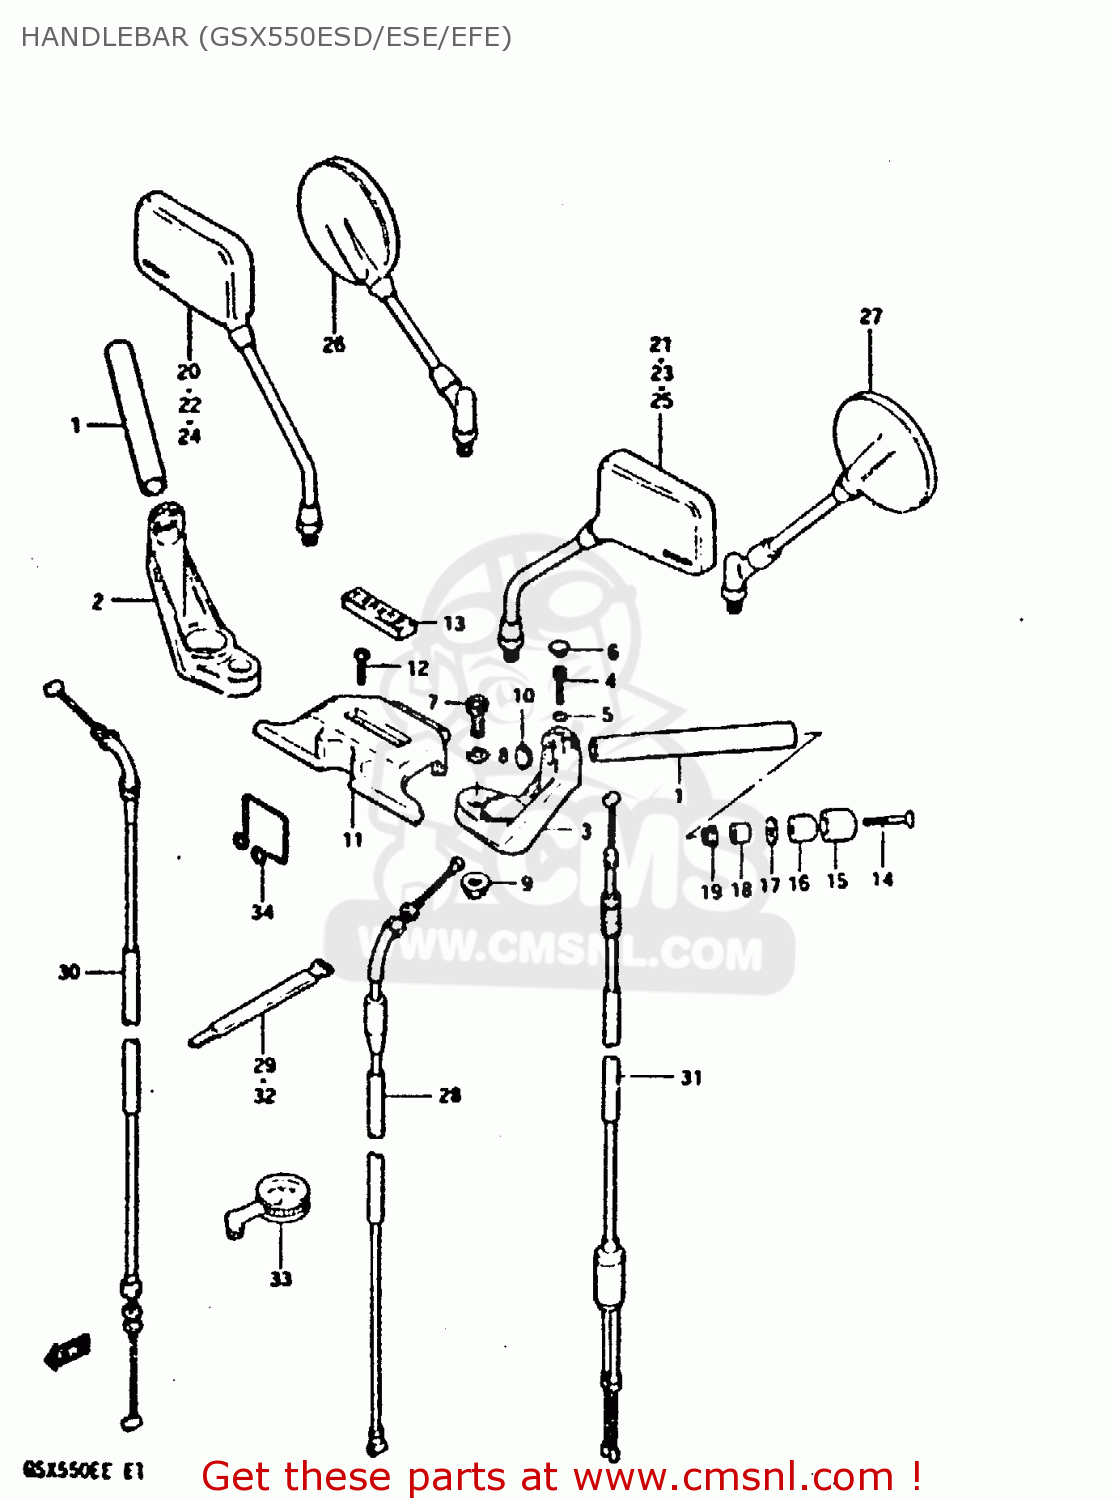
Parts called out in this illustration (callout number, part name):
1	HANDLEBAR
2	HOLDER,HANDLEBAR
3	HOLDER,HANDLEBAR
4	BOLT 8X35
5	WASHER
6	CAP(OD:14.5)
7	BOLT(10X50)
8	WASHER
9	NUT
10	CAP,GRIP END
11	PAD,HANDLEBAR
12	SCREW
13	EMBLEM,HANDLE PAD
14	SCREW 6X55
15	CAP,BALANCER
16	BALANCER,HANDLEBAR
17	SPACER,BALANCER
18	EXPANDER,BALANCER
19	NUT
26	MIRROR ASSEMBLY,RIGHT
27	MIRROR ASSEMBLY,RIGHT
28	MIRROR ASSEMBLY,REAR VIEW
29	MIRROR ASSEMBLY,REAR VIEW
30	CABLE ASSY,CLUTCH
31	CLAMP
32	CABLE ASSEMBLY,THROTTLE
33	CABLE COMP,STARTER
34	CLAMP
35	GAUGE ASSY,AIR PRESSURE
36	GUIDE,CABLE/HARNESS
